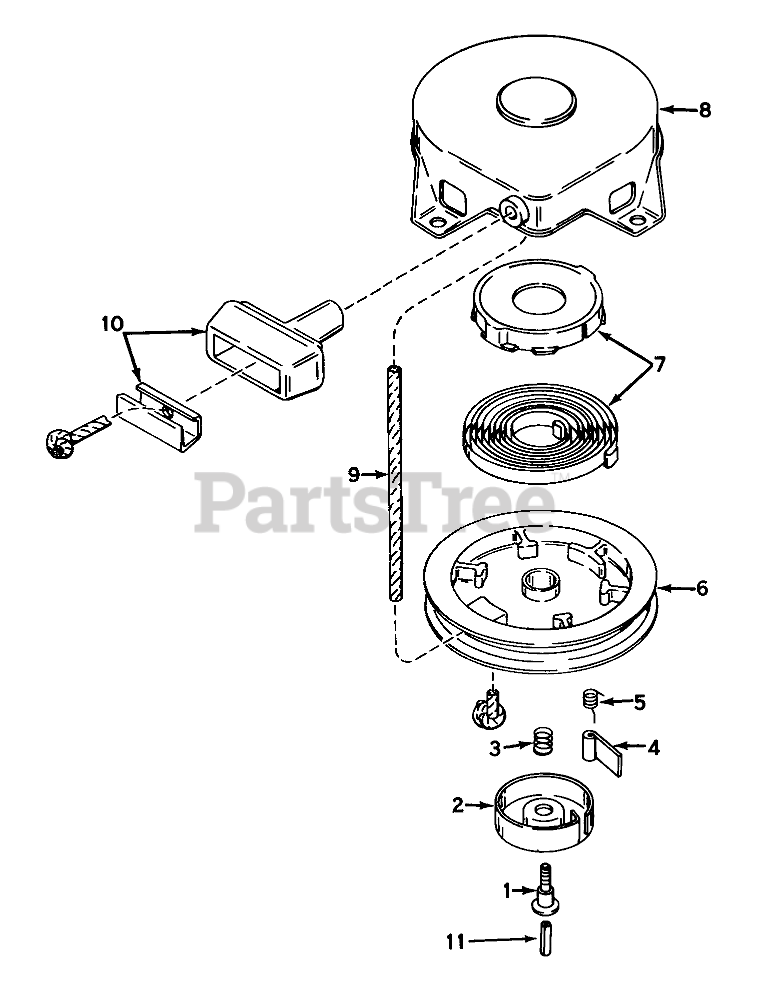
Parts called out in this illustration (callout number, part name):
1	Screw
2	Retainer
3	Spring-Brake
4	Dog-Starter
5	Spring-Dog
7	Spring & Keeper Assy
8	STARTER HOUSING ASSY
9	Rope Starter
10	Assy., Starter
11	Centering
